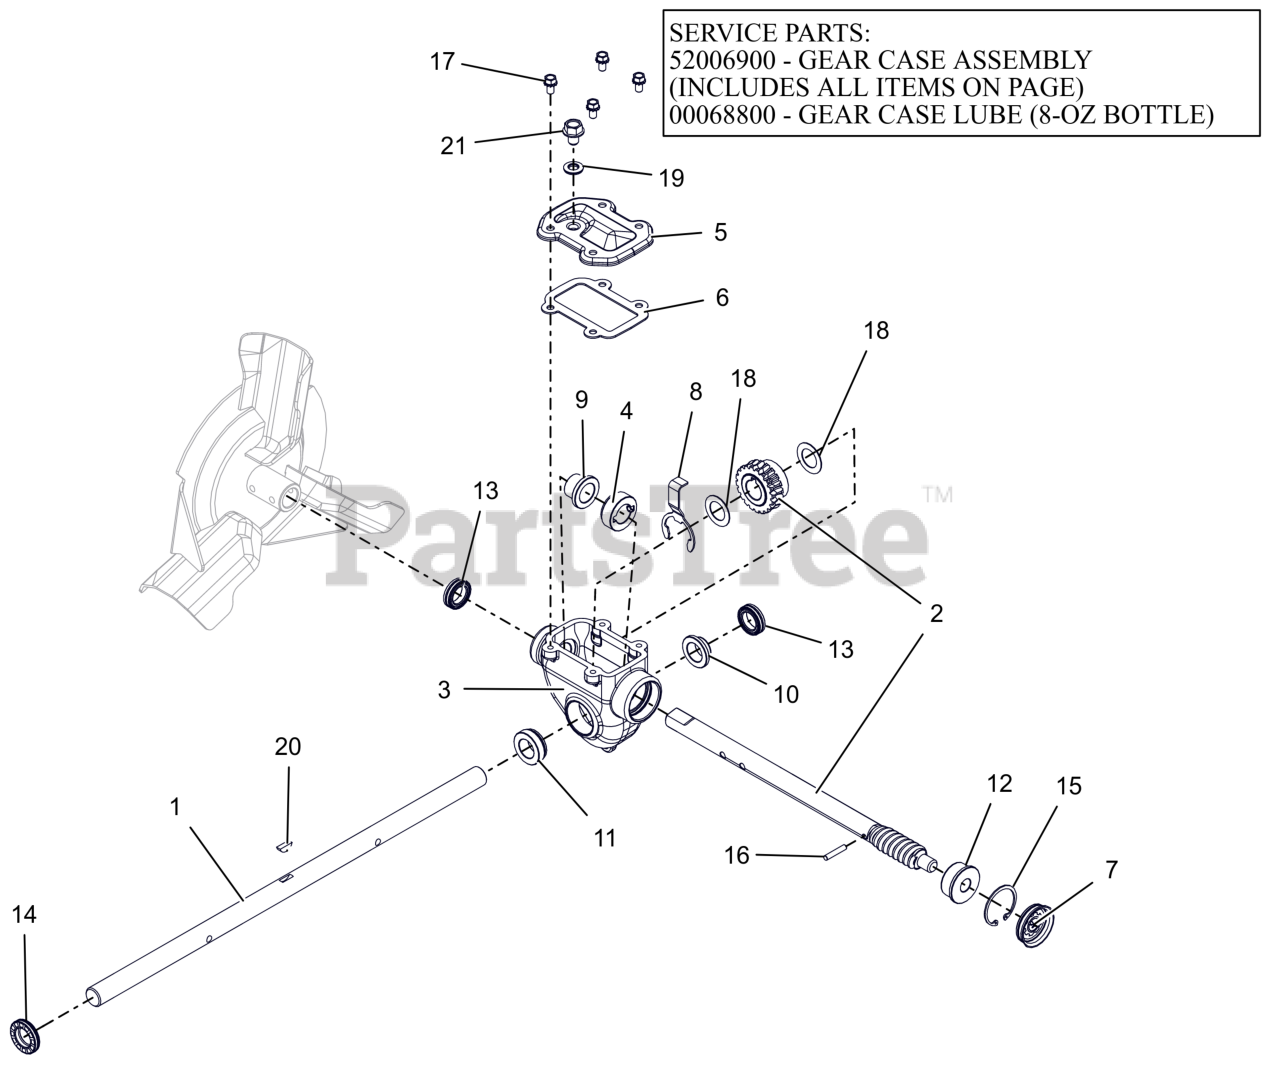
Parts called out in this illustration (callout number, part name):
1	SHAFT, RAKE - 20" (.750 DIA)
2	SHAFT AND WORM GEAR ASSEMBLY
3	GEARCASE, COMPACT MACHINED
3	GEAR CASE, 20" IRON SM TOP-LD
3	ARIENS L3 LUBE, 8 OZ BOTTLE
4	THRUST COLLAR, .75" ID SLIPFIT
5	COVER, TOP - COMPACT
6	GASKET, TOP - COMPACT GEARCASE
7	COVER, GEAR CASE 1.50"
8	BUSHING RETAINER, COMPACT
9	BSHG-FLG .755X.878X.75X1.25
10	BSHG-FLG .755X.878X.424X1.25
11	BSHG-FLG COMPACT, RIGHT
12	BSHG-FLG .503X1.303X.62X1.465
13	SEAL-OIL .748X1.125X.312 TBC29
14	SEAL-OIL .748X1.300X.250 TBC29
15	RG-RTNG-INT 1.500X.050
16	PIN-STR .188X1.00 6150
17	BLT, SEMS .25-20X.50 G5 ZCC
18	WSHR, FLT .760X1.225X.032 ZCC
19	WSHR-BND-SEAL .38X.75X.11 GALV
20	KEY-WDRF .19X.63 HRD #61
21	SCR,TAP .38-15X.50 HWH ROLOK
